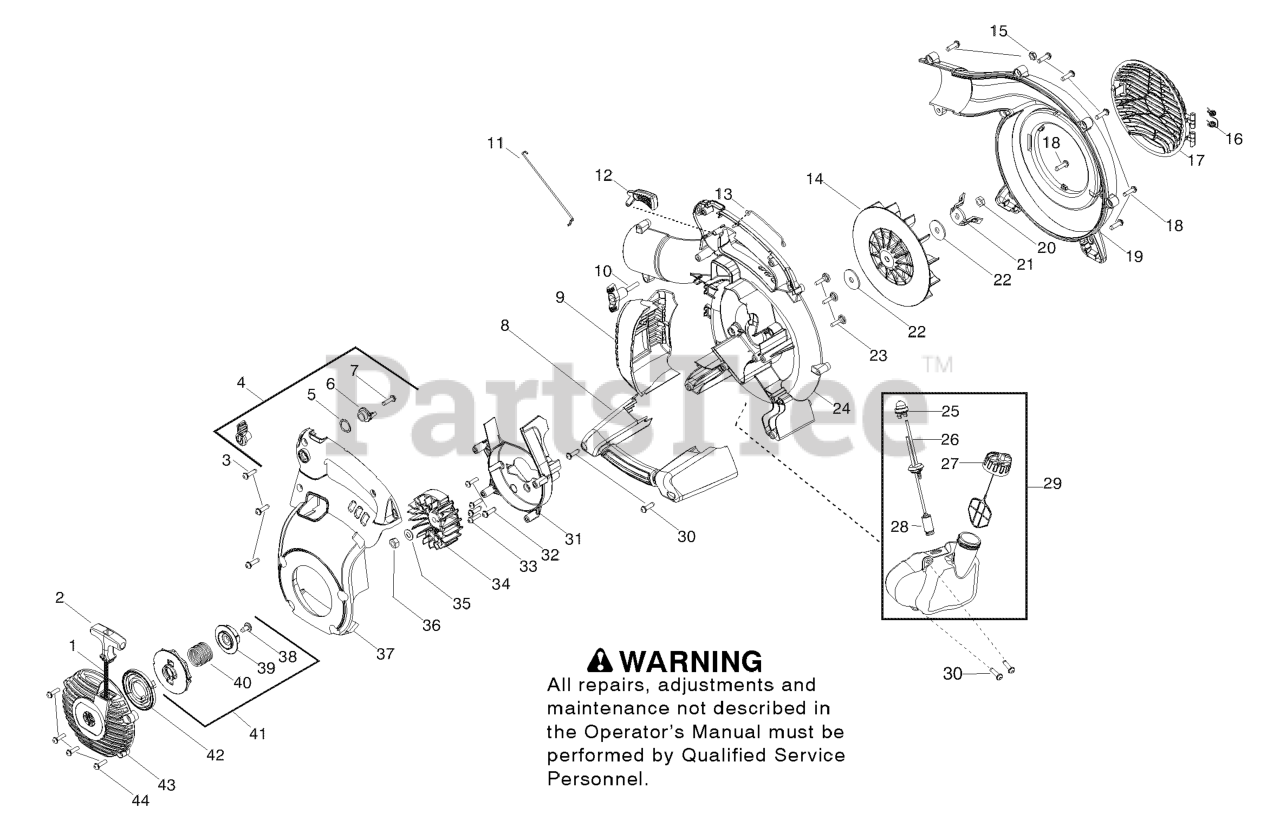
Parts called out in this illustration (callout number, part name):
2	STARTER HANDLE
4	KIT CRUISE CONTROL
5	WAVE WASHER
6	RATCHET CRUISE CONTROL
8	HANDLE ASSIST W/OVER MOLD
9	ASSY, MUFFLER GUARD
10	ASSY, BLOWER KNOB
11	WIRE LINKAGE
12	TRIGGER, THROTTLE
13	WIRE, HANDLE GROUND
14	IMPELLER
16	SPRING, VAC DOOR
17	COVER VAC DOOR
19	ASSY - OUTER SCROLL
20	NUT, IMPELLER
21	BLADE MULCH
22	WASHER IMPELLER
23	SCREW FUEL TANK RETAINER
24	SCROLL - INNER
26	KIT FUEL LINE GROMMET
27	ASSY-CAP W/RETAINER
28	FUEL PICK-UP ASSY
29	ASSY, FUEL TANK
31	SCROLL, FLYWHEEL
33	SCREW - SHROUD
34	ASSY, FLYWHEEL
35	WASHER FLAT
36	NUT-FLYWHEEL
37	COVER - MOTOR HOUSING
40	SPRING EPS2
41	KIT - STARTER
42	SPRING STARTER
43	HOUSING - STARTER COVER
44	SCREW - SHROUD
